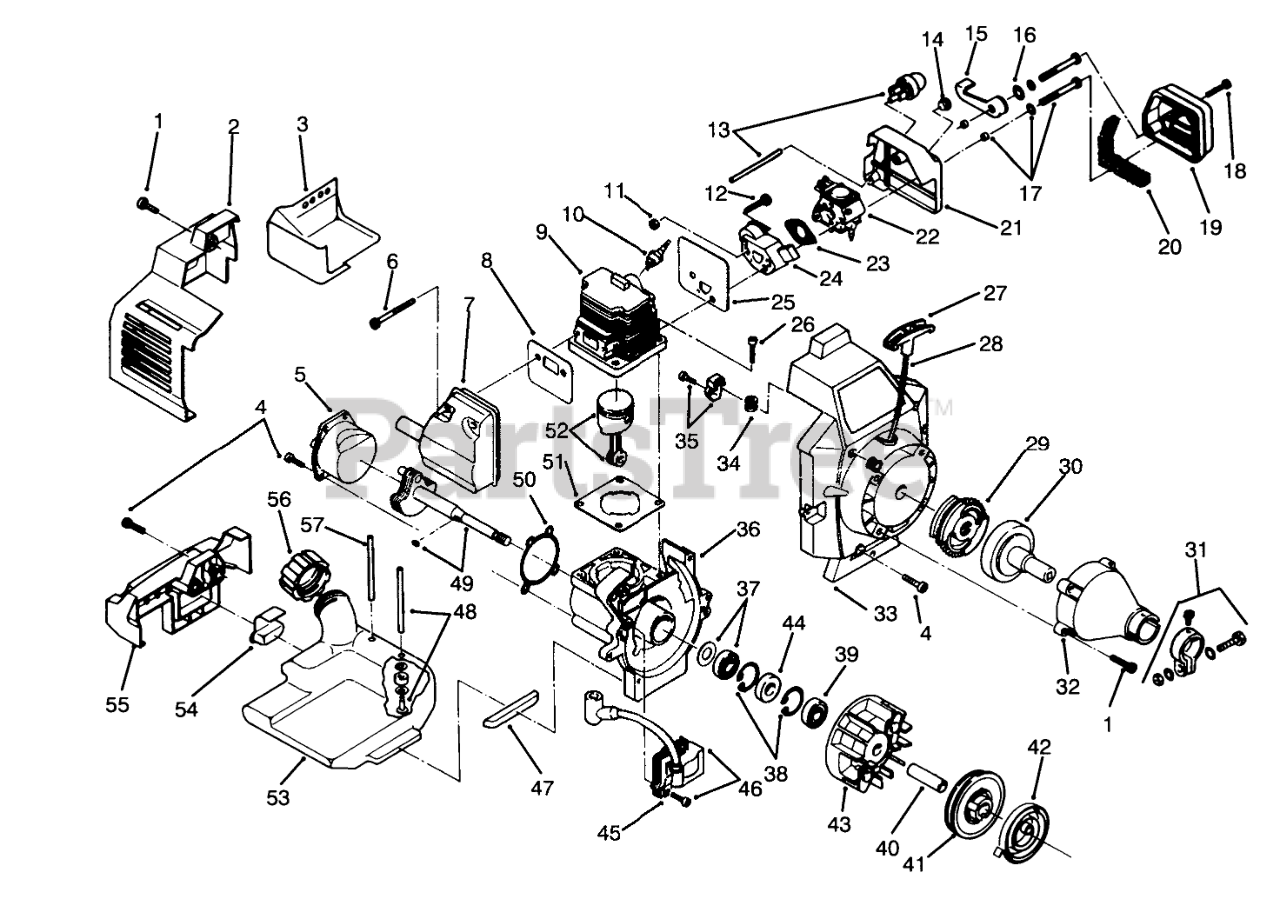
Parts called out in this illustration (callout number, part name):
1	CLUTCH COVER SCREW ASM
2	REAR COVER
3	HEAT SHIELD
4	MOUNTING SCREW SET
5	Cap-Crankcase (Incl. Ref. No. 4)
6	MUFFLER MOUNTING SCREWS
7	Assembly-Muffler (Incl. Ref. No. 8)
8	MUFFLER GASKET
9	Cylinder (Incl. Ref. No. 51)
10	SPARK PLUG
11	SPACER NUT SET
12	SPACER SCREW SET
13	PRIMER & HOSE ASM
14	SWITCH PLUG
15	CHOKE LEVER
16	WAVEY WASHER
17	CARB MOUNTING ASM
18	Screw
19	AIR CLEANER COVER
20	FOAM AIR FILTER ELEMENT
21	Air Cleaner Base Asm.
22	Assembly-Carburetor (Incl. Ref. No. 23)
23	CARB.GASKET(PK.10=1)
24	Assembly-Spacer,Carb. (Incl. Ref. No. 11 & 12)
25	CYL/CARB SPACER GASKET
26	SCREW
27	Handle-Pull
29	Clutch Rotor Asm.
30	CLUTCH DRUM ASM
31	CLAMP ASM - UPPER
32	Assembly-Housing, Clutch (Incl. Ref. No. 1)
33	Assembly-Housing (Incl. Ref. No. 4)
34	ROPE GUIDE
35	PULLEY RETAINER ASM
36	Assembly-Crankcase (Incl. Ref. No. 5, 37-39, 44, 49-50)
37	INNER BEARING ASM
38	Snap ring
39	OUTER BEARING
40	SPACER
41	RECOIL PULLEY
42	RECOIL SPRING
43	Assembly-Flvwheel
45	GROUND TAB
46	MODULE ASM
47	FRONT FUEL TANK PAD
48	FUEL LINE ASM
49	POWER SHAFT ASM
50	CRANKCASE CAP GASKET
51	CYLINDER GASKET
52	PISTON & ROD ASM
53	FUEL TANK ASM
54	REAR FUEL TANK PAD
55	FUEL TANK BRACKET
56	FUEL TANK CAP
57	FUEL RETURN LINE
